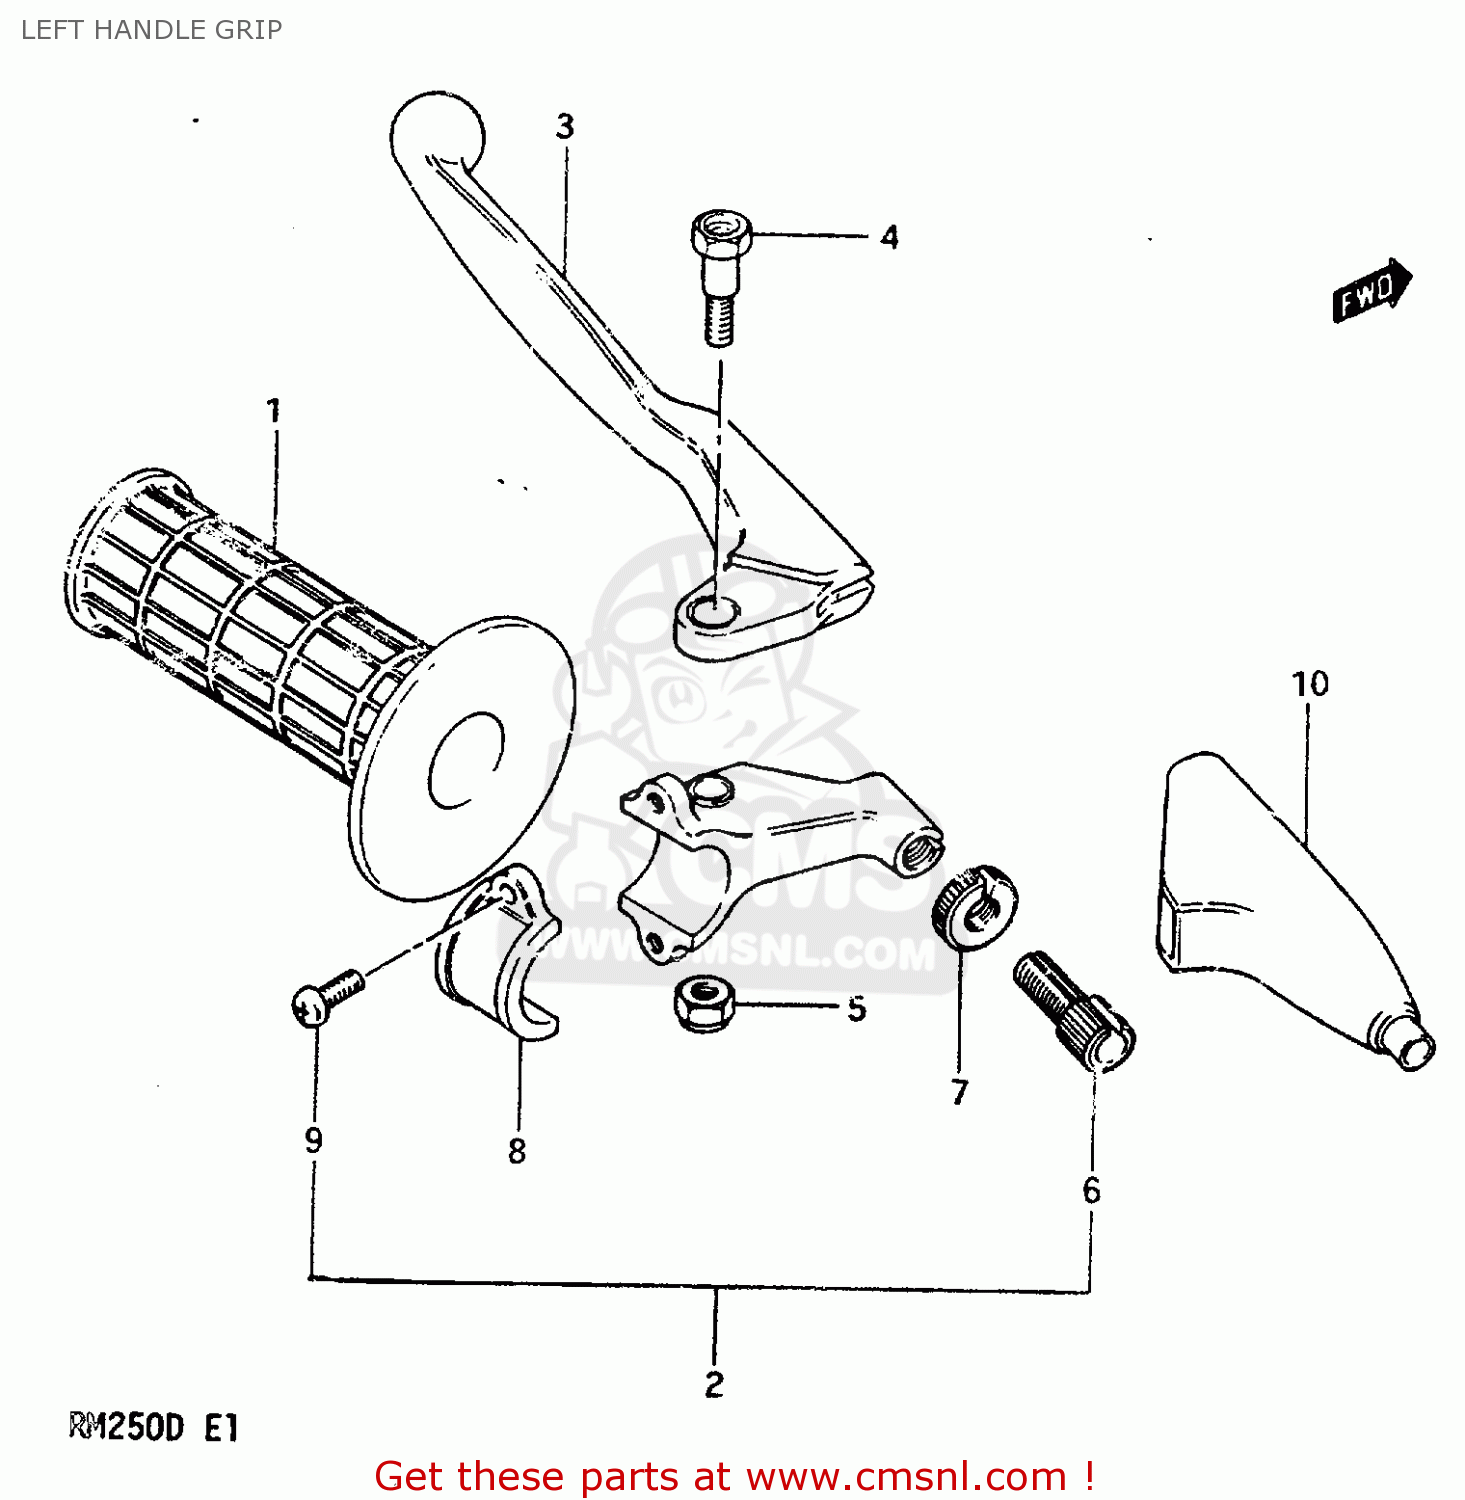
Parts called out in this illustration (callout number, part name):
1	GRIP,LEFT
2	LEVER ASSY,CLUTCH
3	LEVER,CLUTCH
4	BOLT,LEVER
5	NUT 6MM
6	ADJUSTER,CABLE
7	NUT,CABLE ADJUSTER
8	BRACKET,CLUTCH LEVER HOLDER
9	SCREW
10	COVER,CLUTCH LEVER
